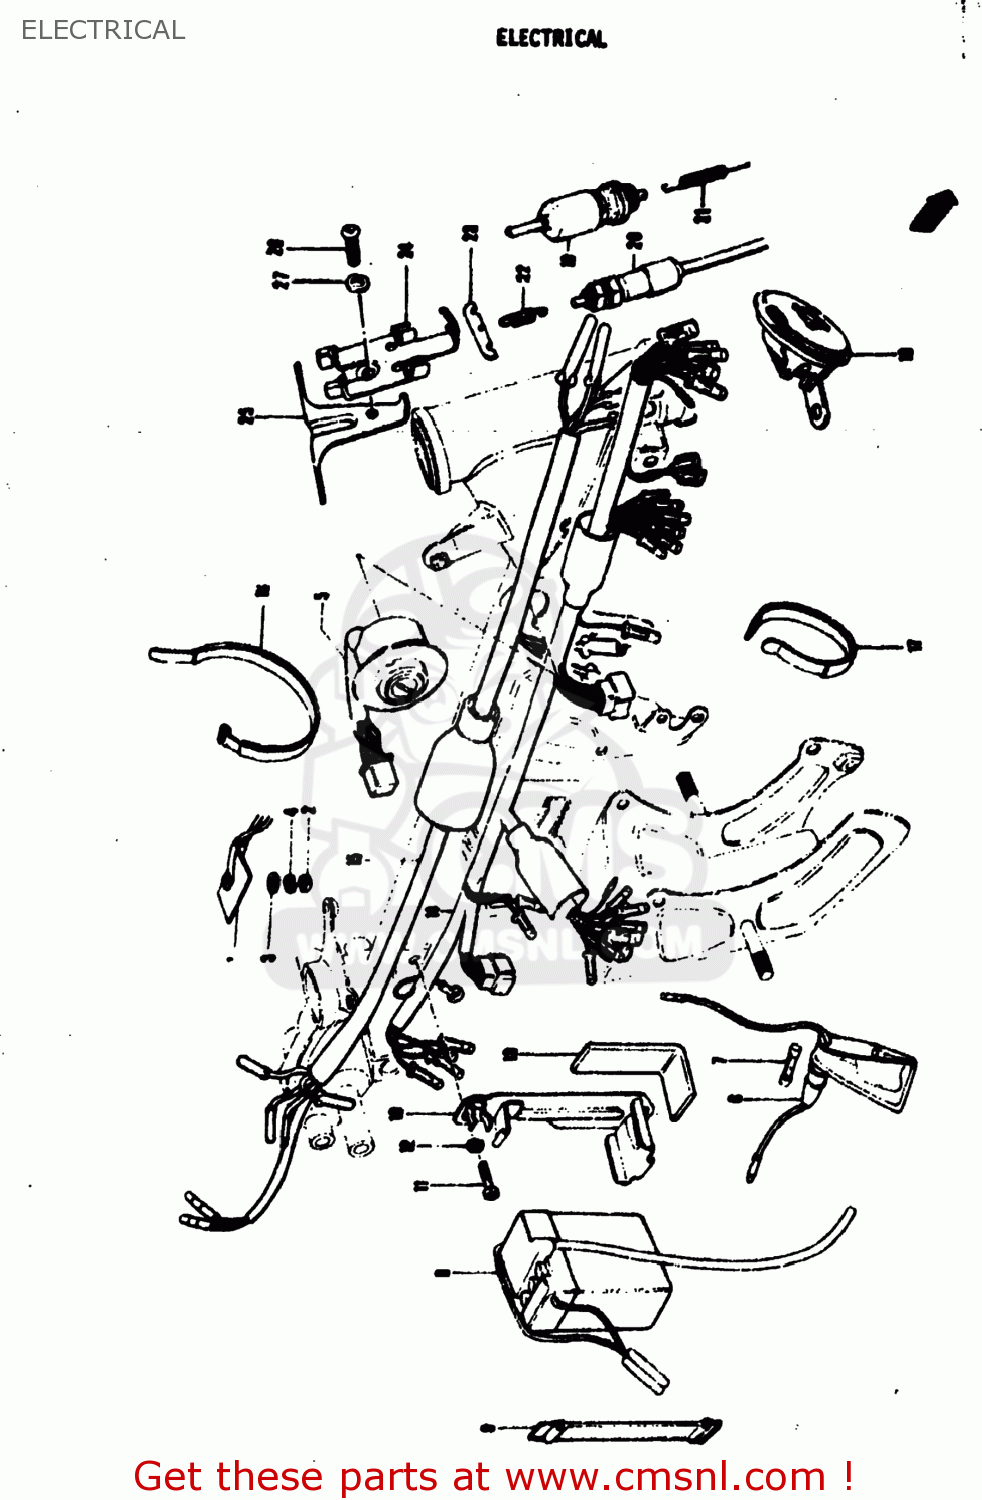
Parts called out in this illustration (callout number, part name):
1	RECTIFIER ASSEMBLY
2	NUT
3	WASHER
4	LOCK WASHER
5	SWITCH, IGNITION
6	BOX ASSEMBLY,FUSE
7	FUSE(15A)
9	BAND
11	SCREW(6X10)
12	LOCK WASHER
15	HARNESS,WIRING
16	CLAMP
17	CLAMP
18	HORN ASSEMBLY
19	SWITCH,BRAKE LAMP
20	SWITCH ASSEMBLY,STOP LAMP
21	SPRING
26	SCREW
27	LOCK WASHER
